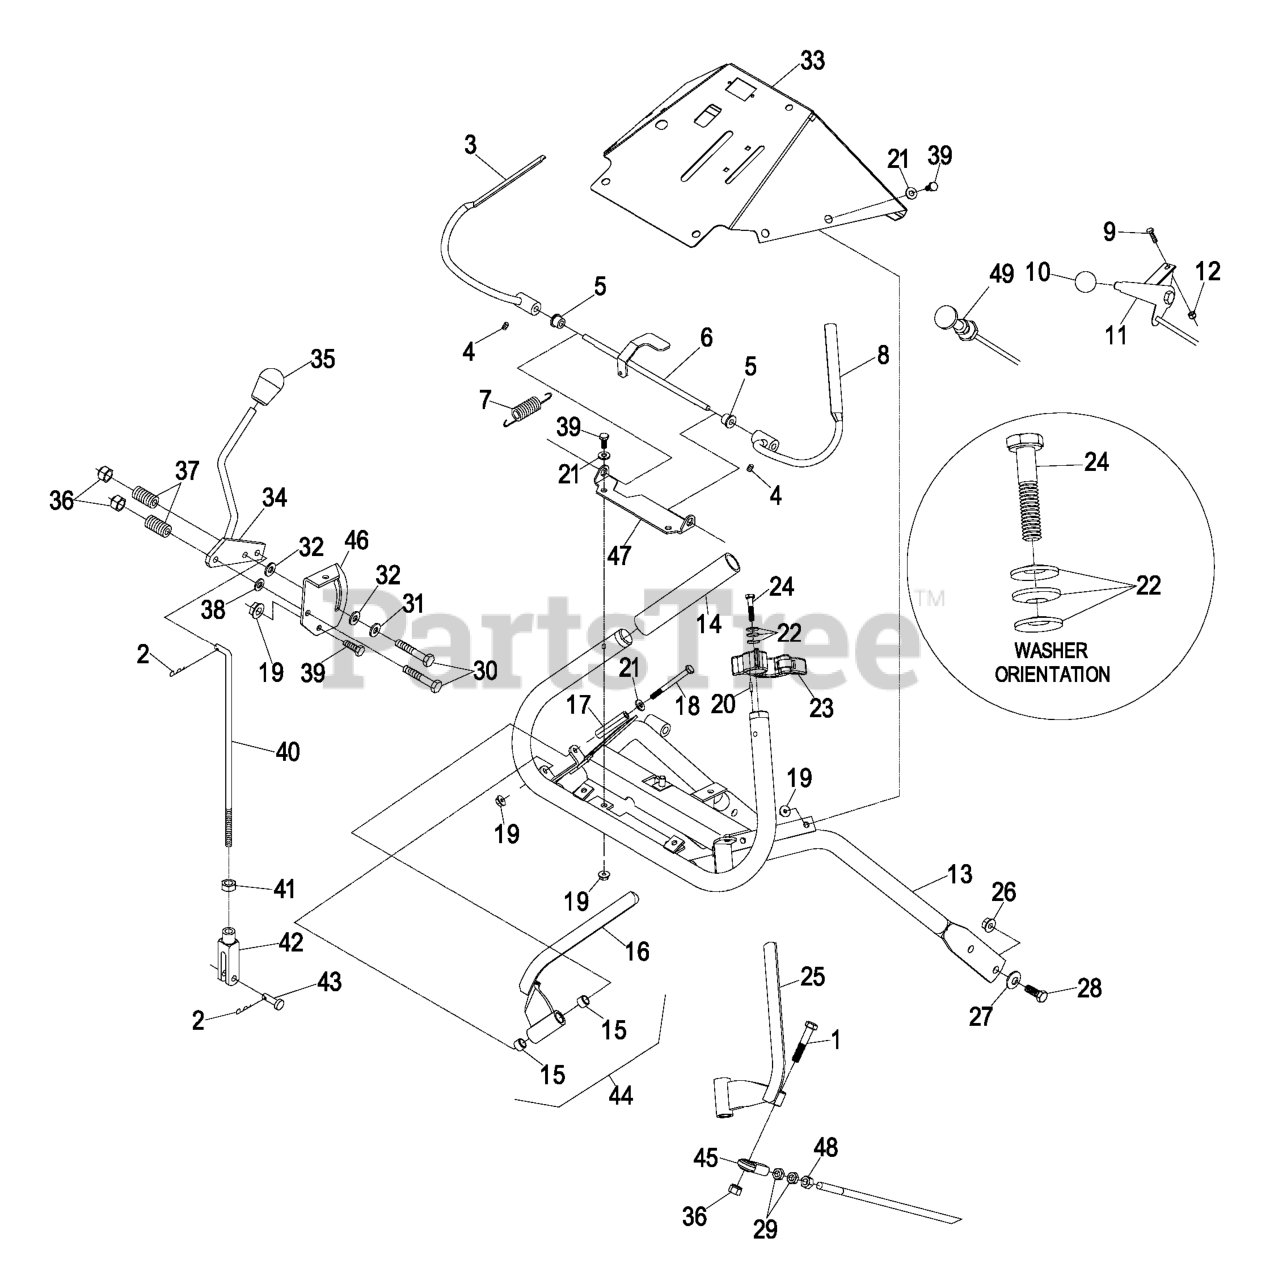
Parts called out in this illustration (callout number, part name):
1	SCREW-HH
2	PIN-COTTER
4	SCREW-SET
5	BUSHING-NYLON
6	WLD,OPC LEVER AXLE
7	SPRING-EXTENSION
9	BOLT-CARR
10	KNOB-BALL
11	THROTTLE CABLE ASM
12	NUT-LOCK, NI
13	WLD,TTH ECS HANDLE
14	GRIP-BAR, HANDLE
15	BUSHING-SLEEVE
17	BUSHING-LEVER, DRIVE
18	SCREW-HH
21	WASHER-FLAT
22	WASHER-SPRING
23	ASM,LATCH RH THUMB
24	SCREW-HH
26	NUT-HHF, WHIZ
27	WASHER-BELLEVILLE
28	SCREW-HH
29	NUT-HJ
30	SCREW-HH
31	WASHER-FRICTION
32	WASHER-FRICTION
33	KIT,TT ECS CONSOLE
35	KNOB, FE.LCKG. BLACK
36	NUT-LOCK, NI
37	SPRING-COMPRESSION
38	WASHER-PLAIN
39	SCREW-HH
40	ROD,SPEED CONTROL
41	NUT-JAM
42	YOKE-ADJUSTABLE
43	PIN-CLEVIS
44	DRIVE LEVER-ASM, RH
45	JOINT-BALL, END
46	BRACKET,SHIFTER SLIDE (PL
47	BRACKET,OPC AXLE
48	NUT-HEX
49	CONTROL-CHOKE
